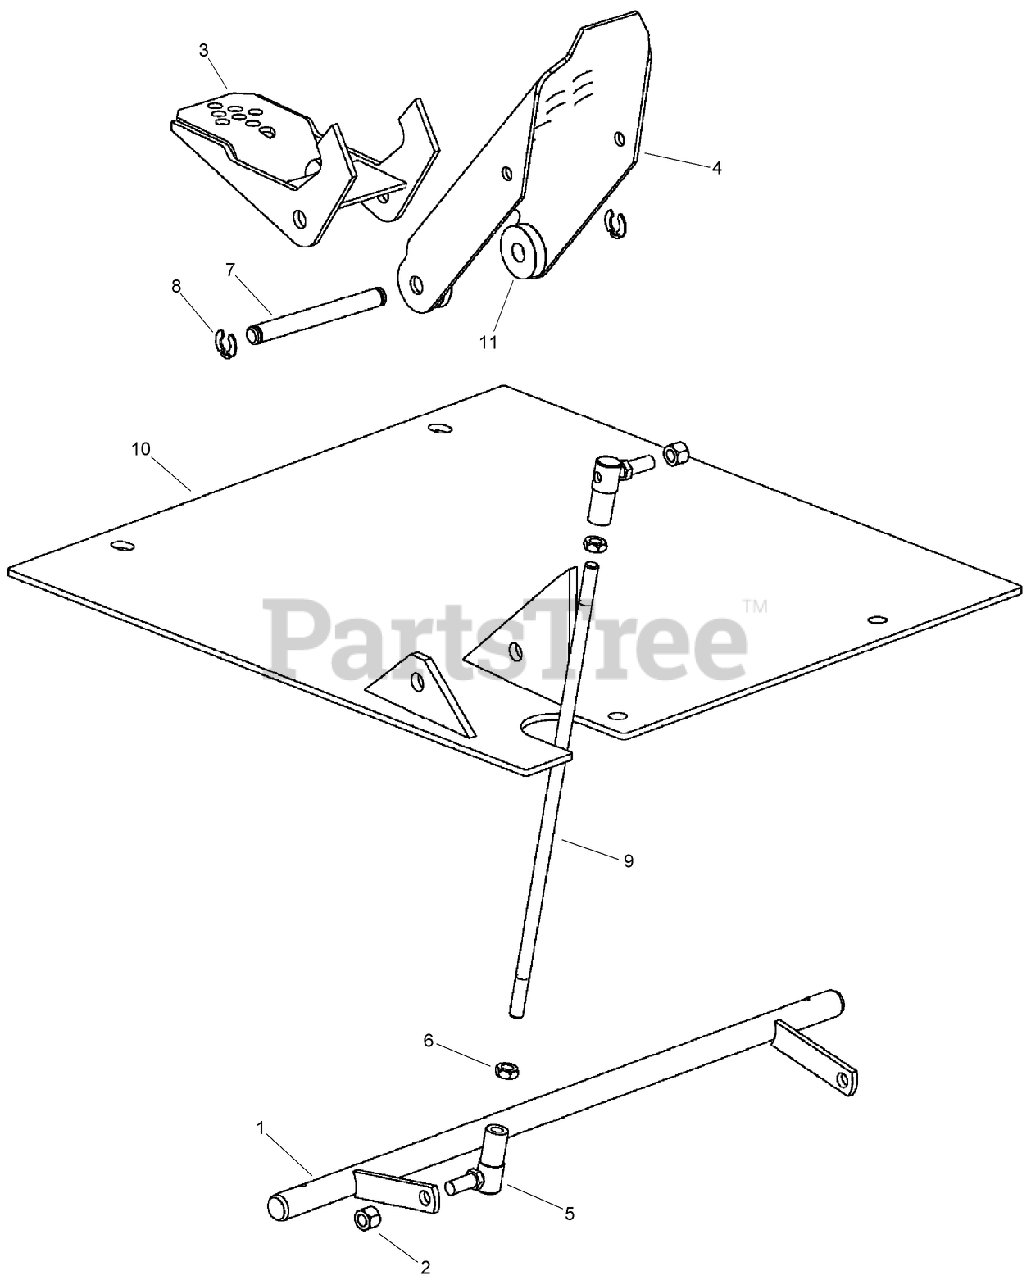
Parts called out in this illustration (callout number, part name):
1	WELDMENT-Control Shaft
2	NUT-HEX
3	PEDAL-Heel
4	PDEAL-Toe
5	JOINT-BALL
6	NUT-JAM, HEX
7	PIN-Pedal
8	RING-Klip 1/2 inch
9	ROD-Control
10	WELDMENT-Floor Plate
11	WASHER
